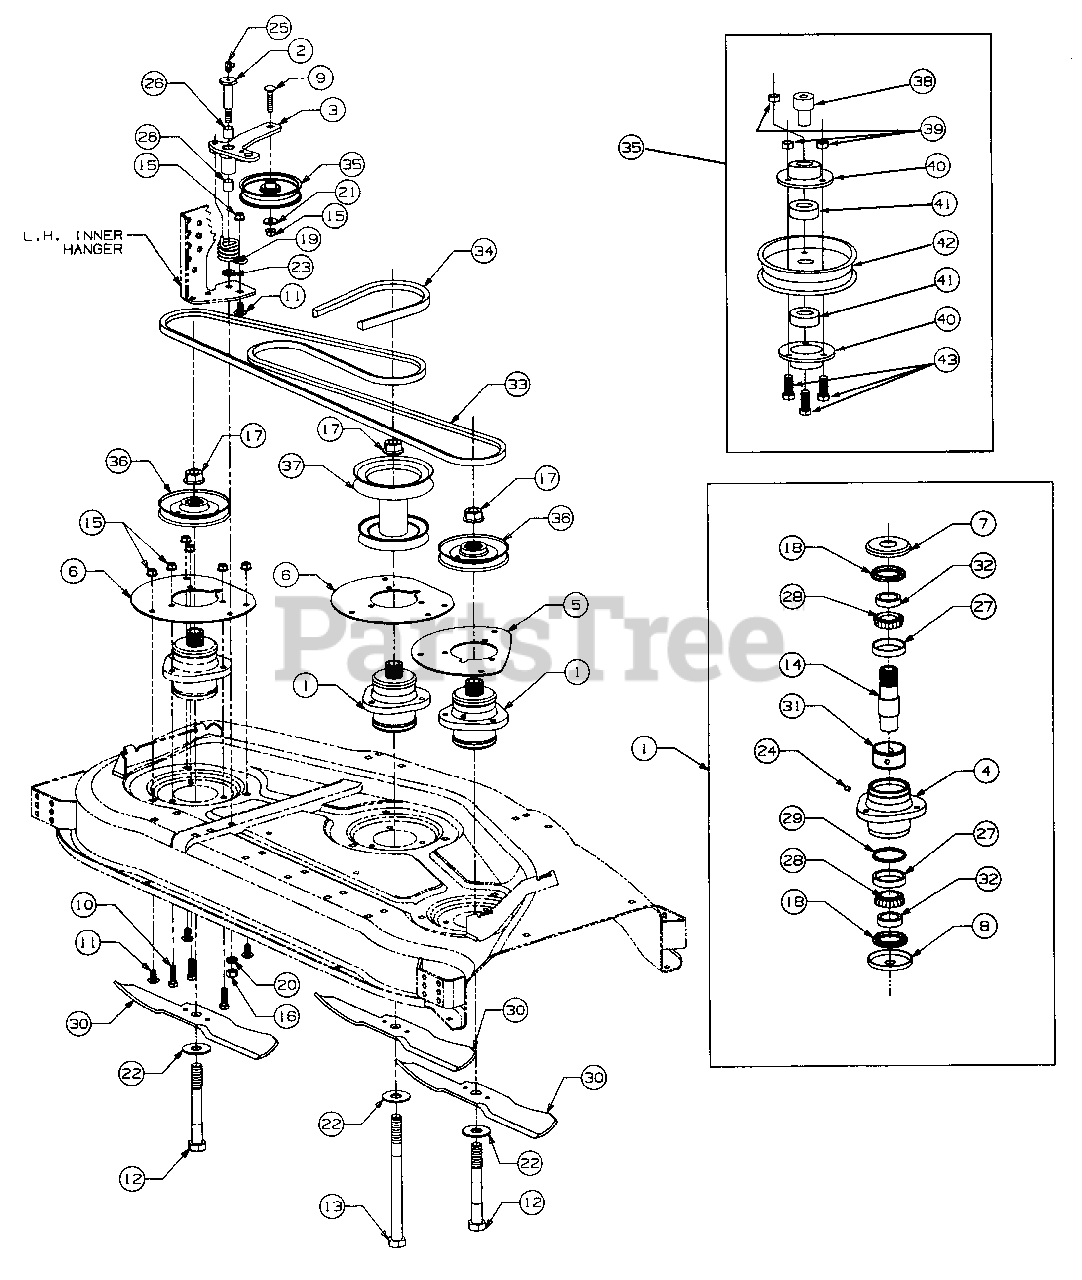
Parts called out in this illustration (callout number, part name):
1	Spindle Assy, Complete
2	Bolt, Shoulder
7	Cup, Top Spindle
9	Bolt, Carriage, 3/8-16 X 1.75 Lg
10	Screw, Hex Cap 3/8-16 X 1.25 Lg GR 5
11	Bolt, Sht Nk Carriage 3/8-16 X .75 Lg GR 5
12	Bolt, Hex Hd Blade, 3/4-16 X 6.0 Lg
13	Bolt, Hex Hd Blade, 3/4-16 X 9.5 Lg
14	Shaft, Blade Spindle
15	Nut, Hex Flanged Lock, 3/8-16
16	Nut, Hex, 7/16-14 GR 5
17	Nut, Hex Flange, 3/4-16
18	Seal, Oil
19	Spring, Torsion
20	Washer, Lock, 7/16
21	Washer, Spec. .378 X 1.0 X .125 Thk
22	Washer, Flat, .781 X 2.0 X .105 Thk
23	Washer, Flat, .469 X .875 X .105 Thk
24	Fitting, Lube
25	Fitting, Lube, 90 degree 1/4-28 Tapper Thd
26	Bearing, Sleeve
27	Cup, Bearing
28	Cone, Bearing
29	Spacer, Bearing
30	Blade, Mower, 16.5 Lg
31	Spacer, Bearing Cup
32	Ring, Seal
33	Belt, Spindle, A-Sect X 107.3 Lg
34	Belt, PTO, B-Sect X 62.04 Lg
35	Pulley Assy, Flat Idler
36	V-Pulley, 4.65 OD
37	Pulley, Deck, 5.07 OD & 5.75 OD
38	Spacer, Shoulder
39	Nut, Hex Insert Lock, 1/4-20
40	Cup, Bearing
41	Bearing, Ball
42	Pulley, Flat Idler
43	Screw, Hex Cap, 1/4-20 X .62 Lg GR5
